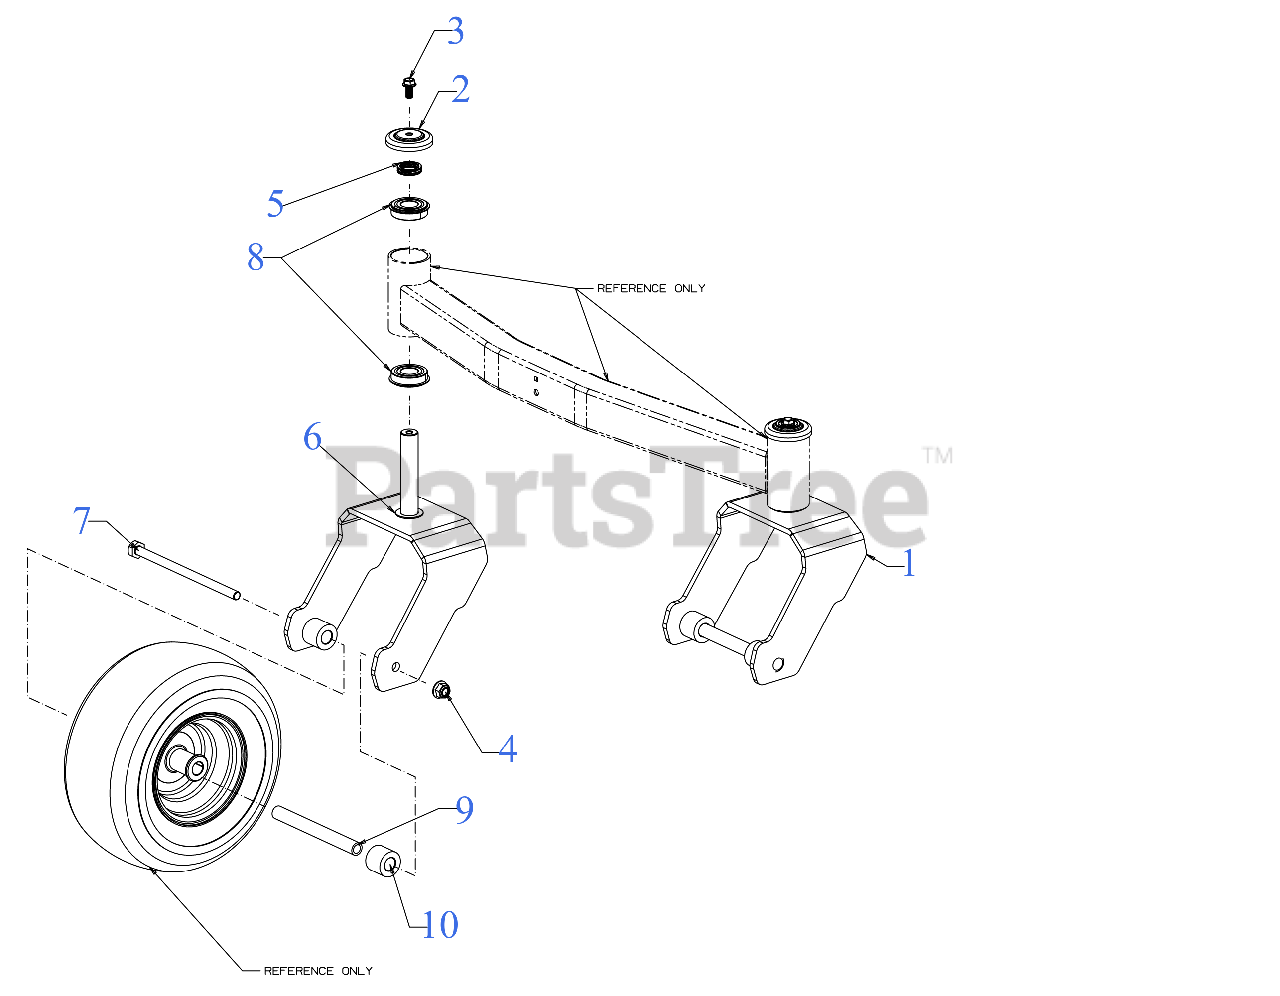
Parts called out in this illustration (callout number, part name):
1	CASTER WHEEL YOKE
3	BOLT - 3/8-16:.75:GR5:PATCH LOCK
5	WAVE WASHER
6	WASHER 1.010X1.560X.060
7	SCREW-1/2-13X8.5 GR5 FLG RZF-SX
8	BALL BEARING 25X52X15
9	CASTER AXLE SPACER
10	CASTER WHEEL SPACER
